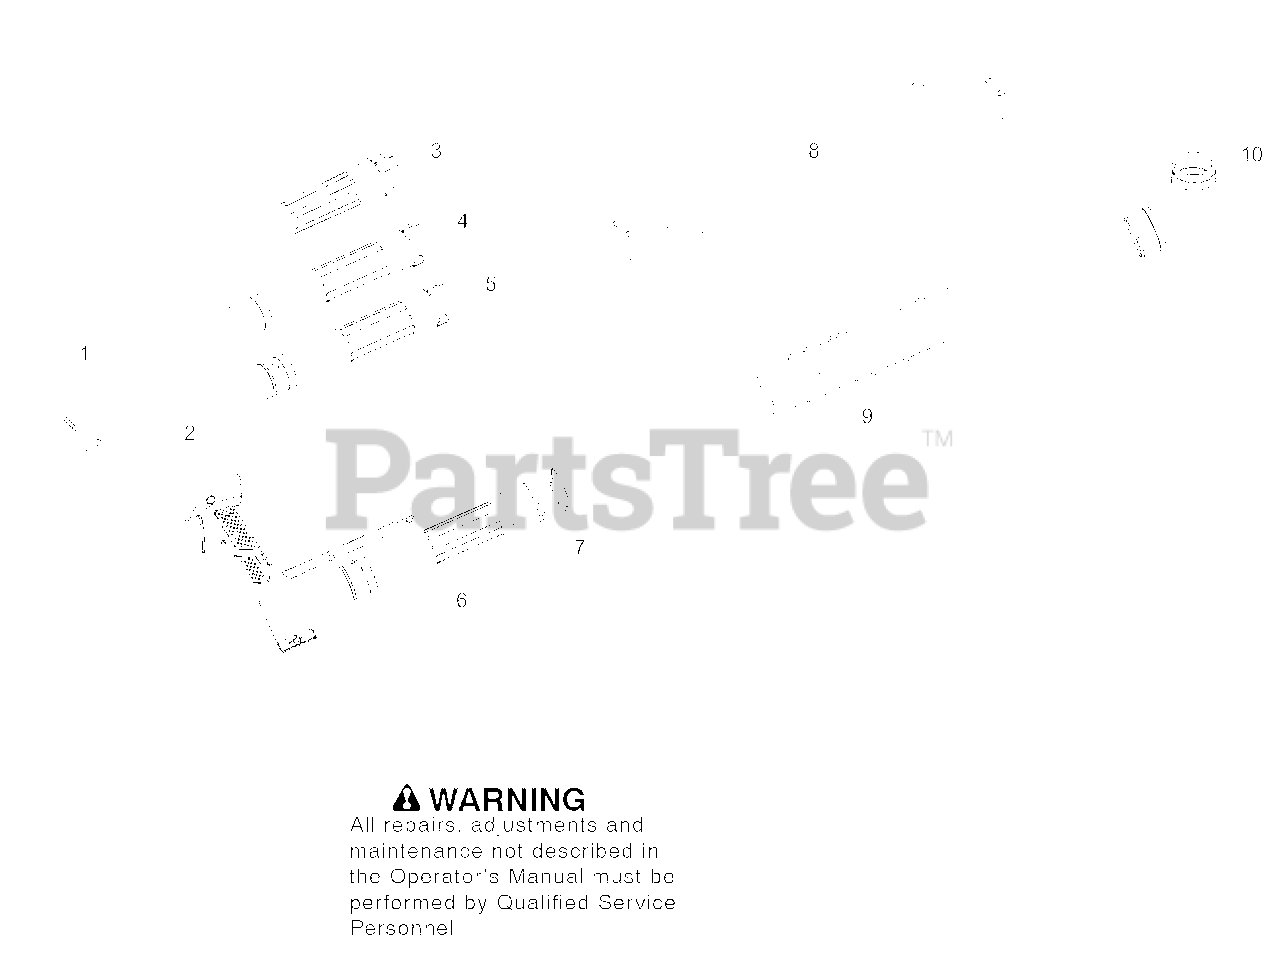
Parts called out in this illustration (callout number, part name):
1	Kit - Throttle Retention
2	Assembly - Throttle Lever
3	40mm End Pipe
4	56mm End Pipe
5	Middle Pipe
6	Base Pipe
7	Active Ring
8	Kit - Clamp
9	Flex Pipe
10	Elbow Pipe
